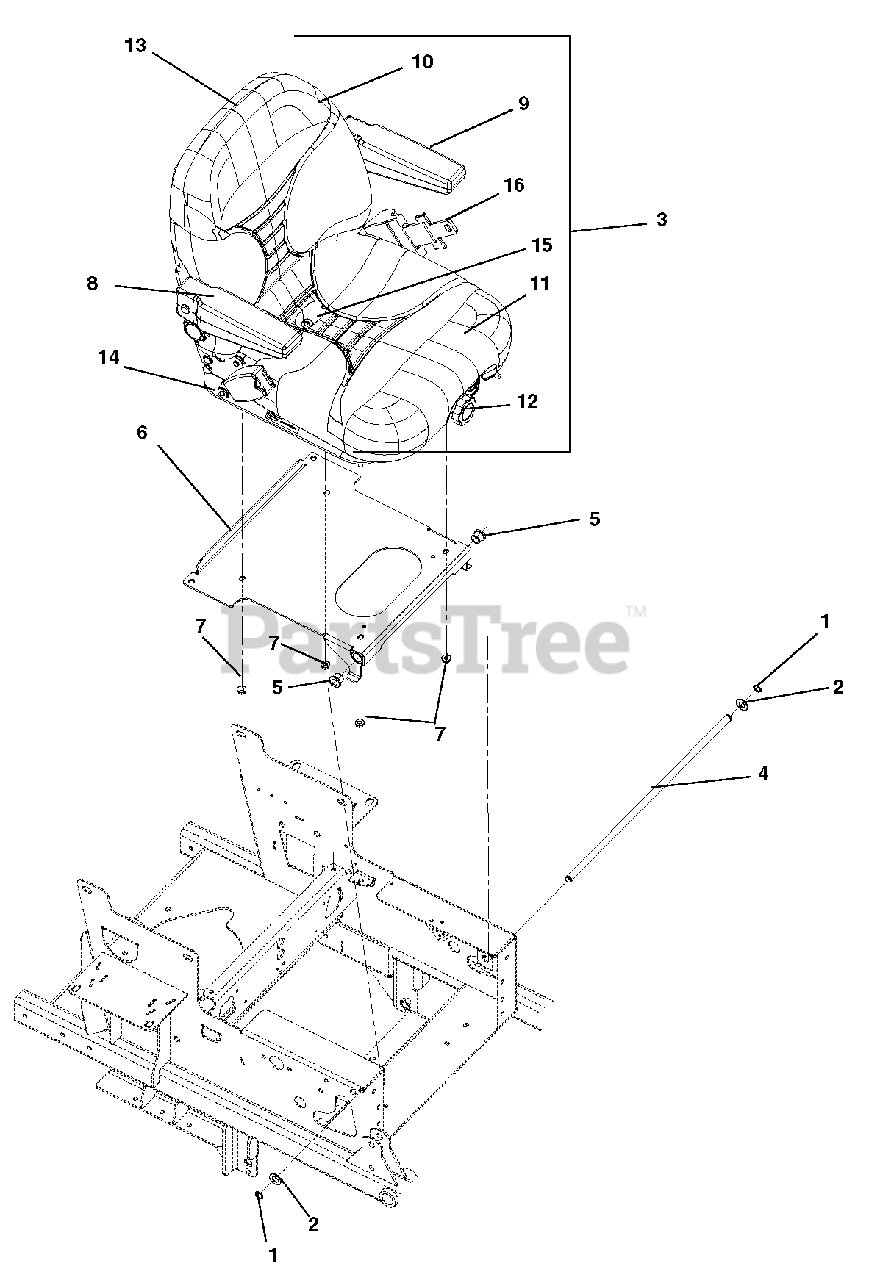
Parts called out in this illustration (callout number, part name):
1	Ring, Retaining-External .500 x .050
2	Washer, Flat Steel .531 x 1.00 x .063
3	Seat, Suspension - with Belt, Light Gray
4	Shaft, 100I Seat Pivot
5	Bushing, Flange .516 x .750 x .625 x .937
6	Seat Plate Weldment
7	Nut, Locking-Top-Flange .31-18
8	Kit, Right Hand Armrest Assembly
9	Kit, Left Hand Armrest Assembly
10	Kit, Back Cushion, Light Grey
11	Kit, Seat Cusion, Light Grey
12	Kit, Seat Knobs
13	Kit, Seat Back
14	Kit, Seat Slides
15	Kit, Seat Spring and Saddle
16	Kit, Retractable Safety Belt
